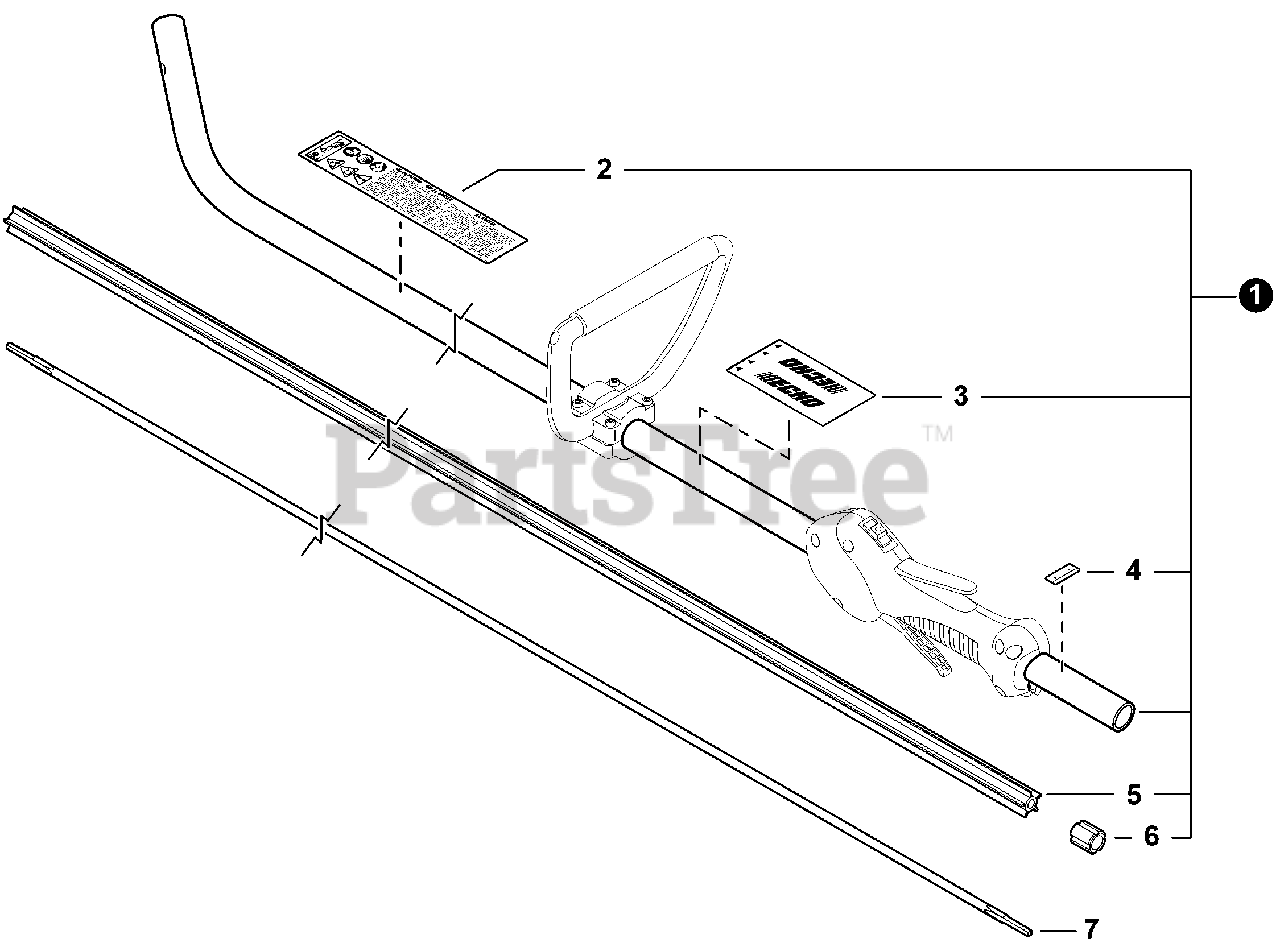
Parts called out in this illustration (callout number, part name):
1	MAIN PIPE ASSY
2	LABEL, CAUTION
3	LABEL, HANDLE LOCATION
4	LABEL - ALIGNMENT
5	LINER, FLEXIBLE 21.6×1420
7	DRIVESHAFT - FLEXIBLE
